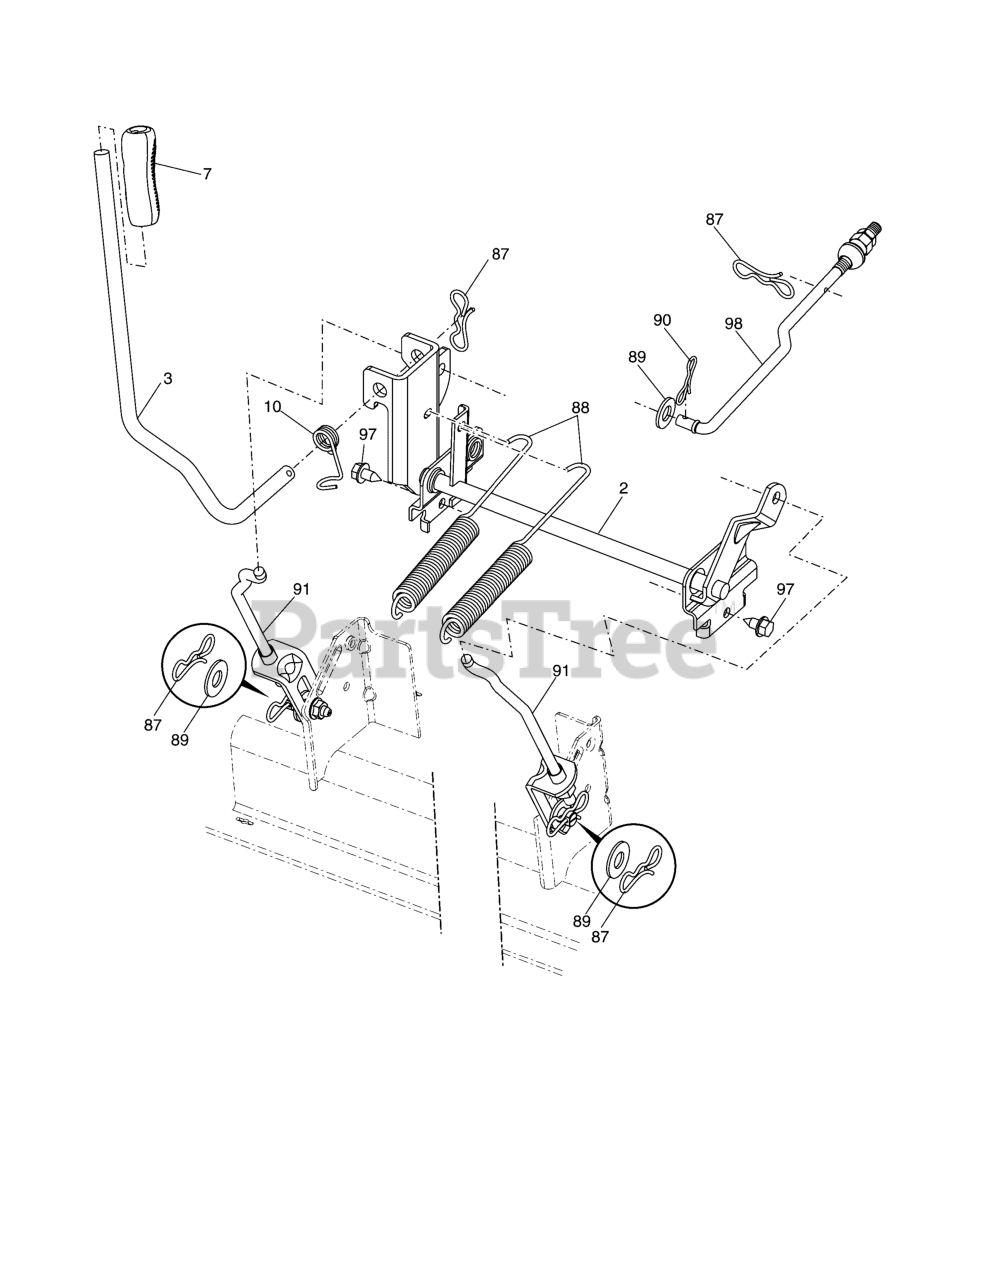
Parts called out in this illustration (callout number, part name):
2	Shaft Asm., Lift
3	Lever Asm., Lift RH
7	Grip, Lever
10	Spring Torsion
87	Pin Cotter 7/16 Bow Tie Lock
88	Spring Lift Assist
89	Washer Clear Zinc
90	Pin Cotter 5/16 Bow Tie Lock
91	Link Lift Susp Mower Rear
97	Screw 3/8-16 x 3/4
98	Link Lift Susp. Front Mower
